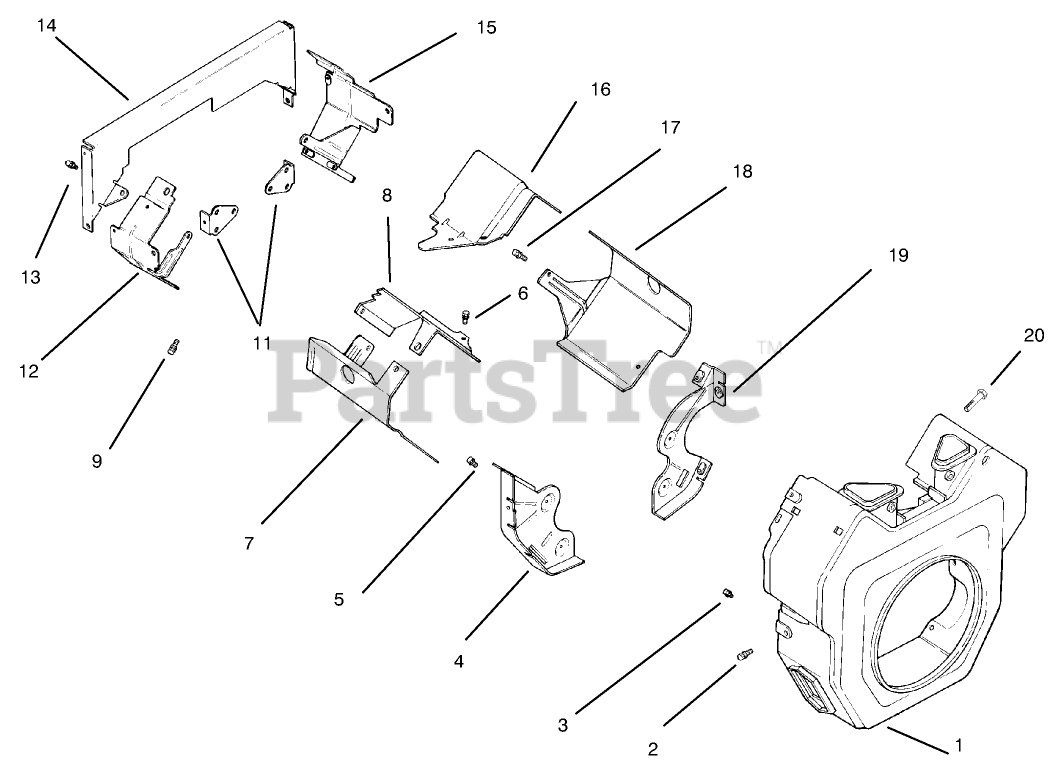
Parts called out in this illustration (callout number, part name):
1	Housing-Blower
2	Screw
3	Screw
4	Plate-Backing #2 side
5	Screw
6	Screw
7	Baffle-Barrel, Cylinder (No. 2 Side)
8	Baffle-Valley (No. 2 Side)
9	Screw
10	Kit-"Q"Duct (Incl. Ref. #11-15)
11	Bracket-Support
12	Baffle-Air, Ducted (No. 1 side)
13	Screw
14	Plate-Air Backing, Ducted
15	Baffle-Air, Ducted (No. 2 side)
16	Baffle-Valley, No. 1 side
17	Screw
18	Baffle-Cylinder Barrel #1 side
19	Plate-Backing #1 side
20	Screw
